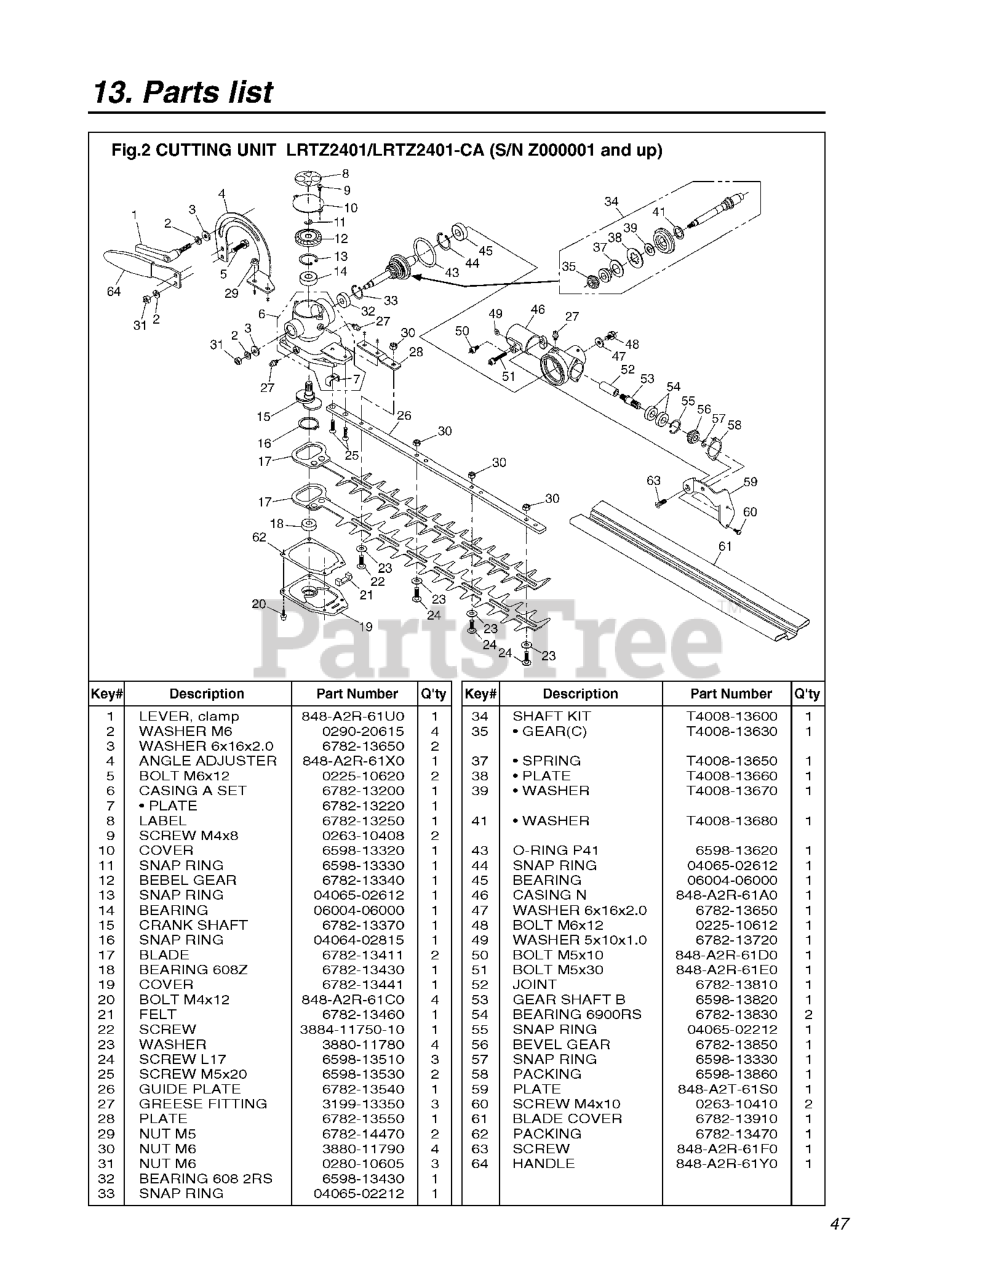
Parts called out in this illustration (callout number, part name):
1	CLAMP LEVER M6X16MM
4	ANGLE ADJUSTER
6	CASE(A) SET
10	COVER(A)
13	RING,SNAP M26x1.2 RP-318013340
15	CRANKSHAFT
16	RING, SNAP, M28 x 1.5
17	UPP-LOW-BLADE
18	BEARING
22	SCREW(R3873,388411750&11770
24	SCREW.L17
25	SCREW.5X20
29	RP_NUT
33	RING, SNAP, M22 x 1.2
35	GEAR (C)
37	WASHER, SPRING
44	RING,SNAP M26x1.2 RP-318013340
46	CASING N***
50	BOLT M5X10
51	BOLT M5X30
53	GEARSHAFT(B)
55	RING, SNAP, M22 x 1.2
